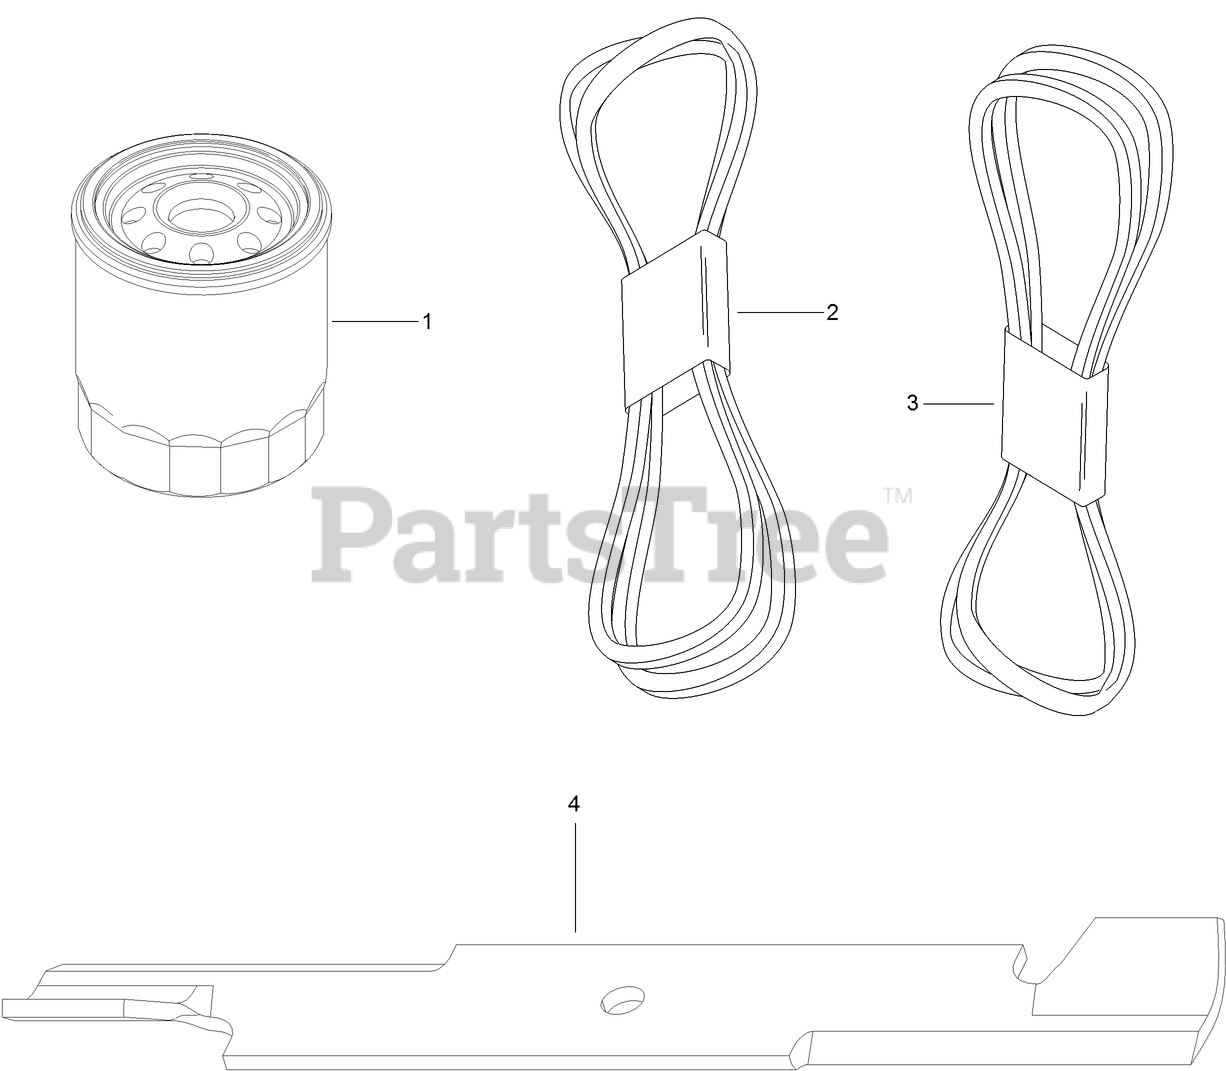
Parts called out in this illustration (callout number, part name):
1	ELEMENT-OIL FILTER, HYD
2	BELT-V
3	BELT-DECK DRIVE
4	BLADE-ROTARY, 20.5IN (HI FLOW)
